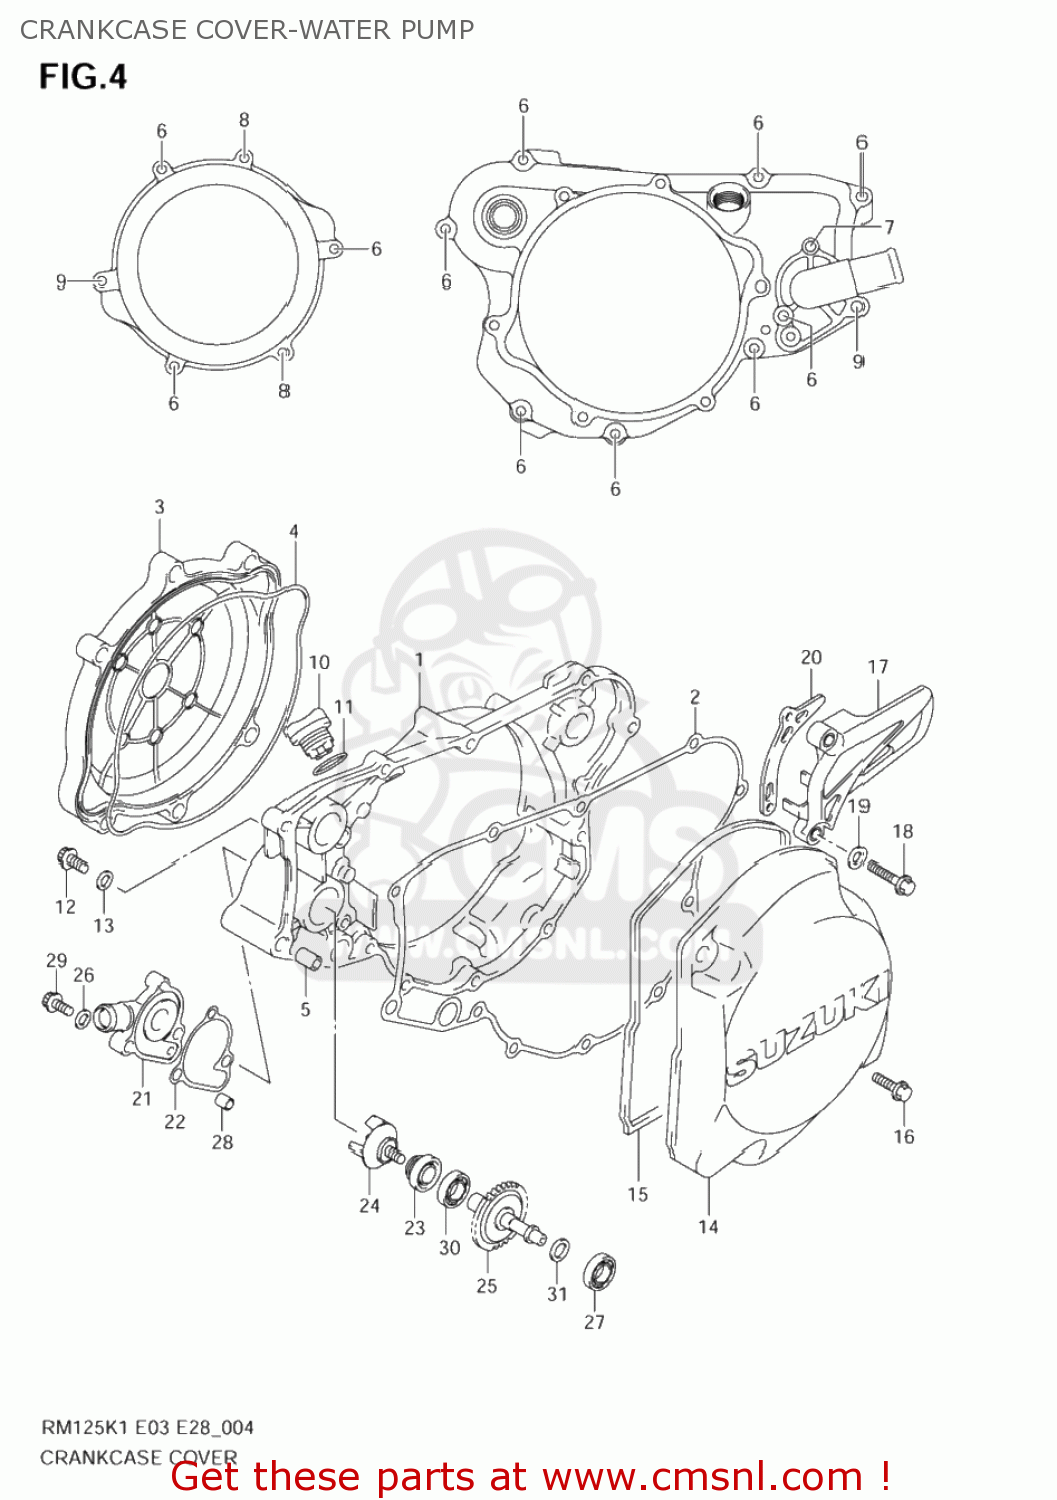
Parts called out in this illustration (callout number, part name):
1	COVER,CLUTCH
2	GASKET,CLUTCH COVER (NAS)
3	COVER,CLUTCH O
4	O RING,CLUTCH COVER OUTER
5	PIN
6	SCREW
7	BOLT(6X30)
8	BOLT
9	BOLT
10	PLUG,ENGINE OIL FILLER
11	O RING(D:3.1,ID:16.8)
12	BOLT
13	GASKET(6.2X11X1).2 (NAS)
14	COVER,MAGNETO
15	GASKET,MAGNETO COVER
16	SCREW
17	COVER,ENGINE SPROCKET
18	BOLT(6X30)
19	WASHER
20	PLATE,FR CHAIN GUIDE
21	CASE,WATER PUMP
22	GASKET,WATER PUMP CASE (NAS)
23	SEAL,WATER PUMP OIL
24	IMPELLER,WATER PUMP
25	SHAFT,WATER PUMP
26	GASKET(6.2X11X1).2 (NAS)
27	BEARING(8X22X7)
28	PIN
29	BOLT
30	BEARING
31	WASHER
